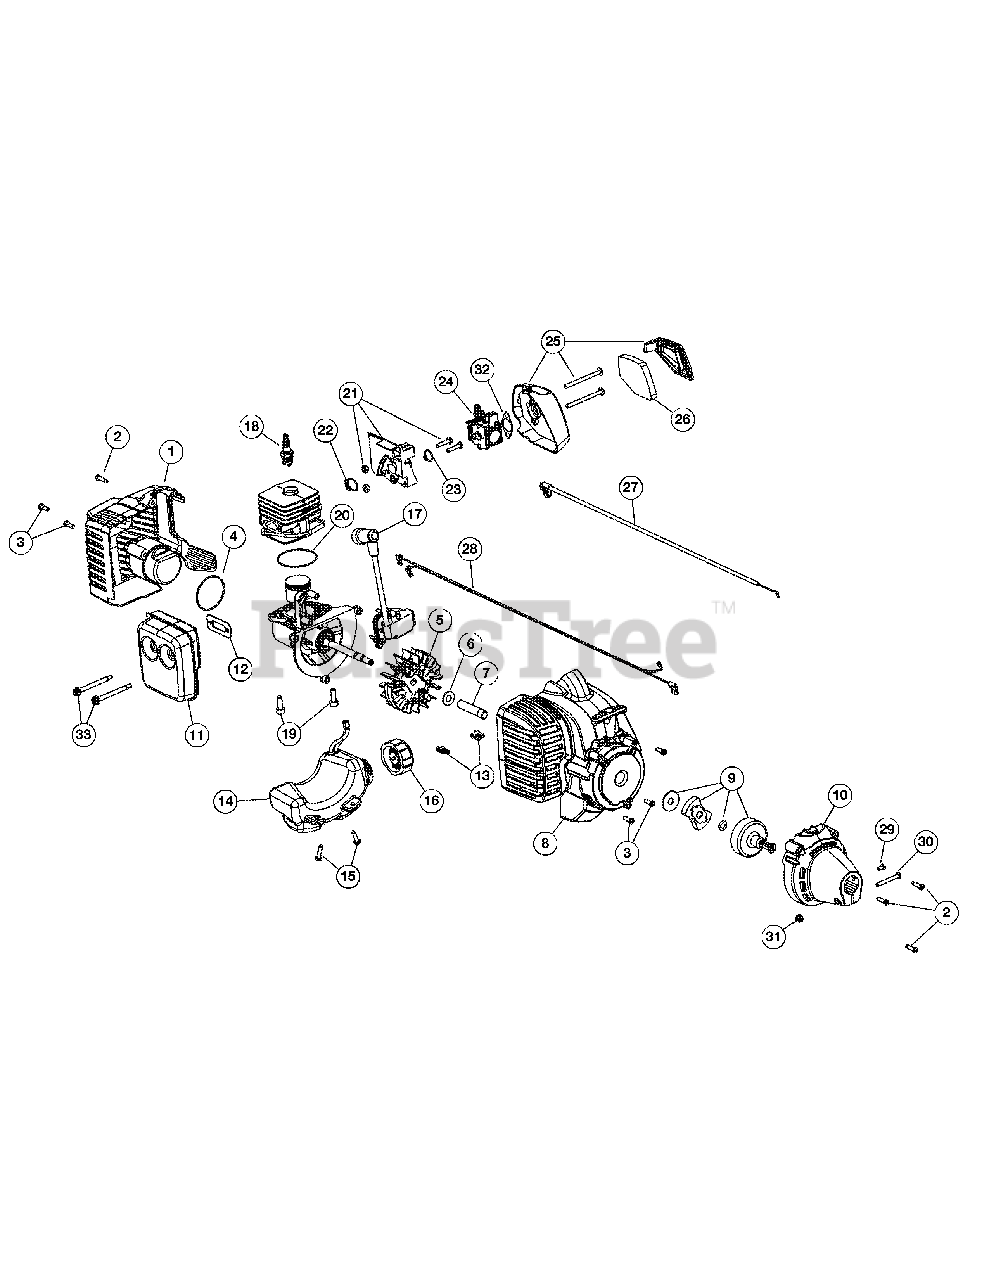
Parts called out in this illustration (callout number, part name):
1	Rear Cover Assembly (Incl. Ref No. 2 & 3)
2	Cover Screw
3	Housing Screw
4	O-Ring
5	Flywheel Assembly
6	Washer
7	Spacer
8	Starter Housing (Incl. Ref No. 3 & 13)
9	Clutch Assembly
10	Clutch Cover (Incl. Ref No. 2)
11	Muffler Assembly (Incl. Ref No. 12 & 33)
12	Muffler Gasket
13	U-shaped Nut
14	Fuel Tank Assembly (Incl. Ref No. 15 & 16)
15	Tank Screw
16	Fuel Cap
17	Module Assembly
18	Spark Plug
19	Crankcase Bolt
20	Crankcase O-Ring
21	Insulator Assembly (Incl. Ref No. 22 & 23)
22	Insulator O-Ring
23	Carburetor O-Ring
24	Carburetor
25	Aircleaner Cover Assembly (Incl. Ref No. 26)
26	Aircleaner Filter
27	Throttle Cable
28	Lead Wires
29	Anti-rotation Screw
30	Clamp Screw
31	Clamp Nut
32	Air Cleaner Gasket
33	Muffler Screw
